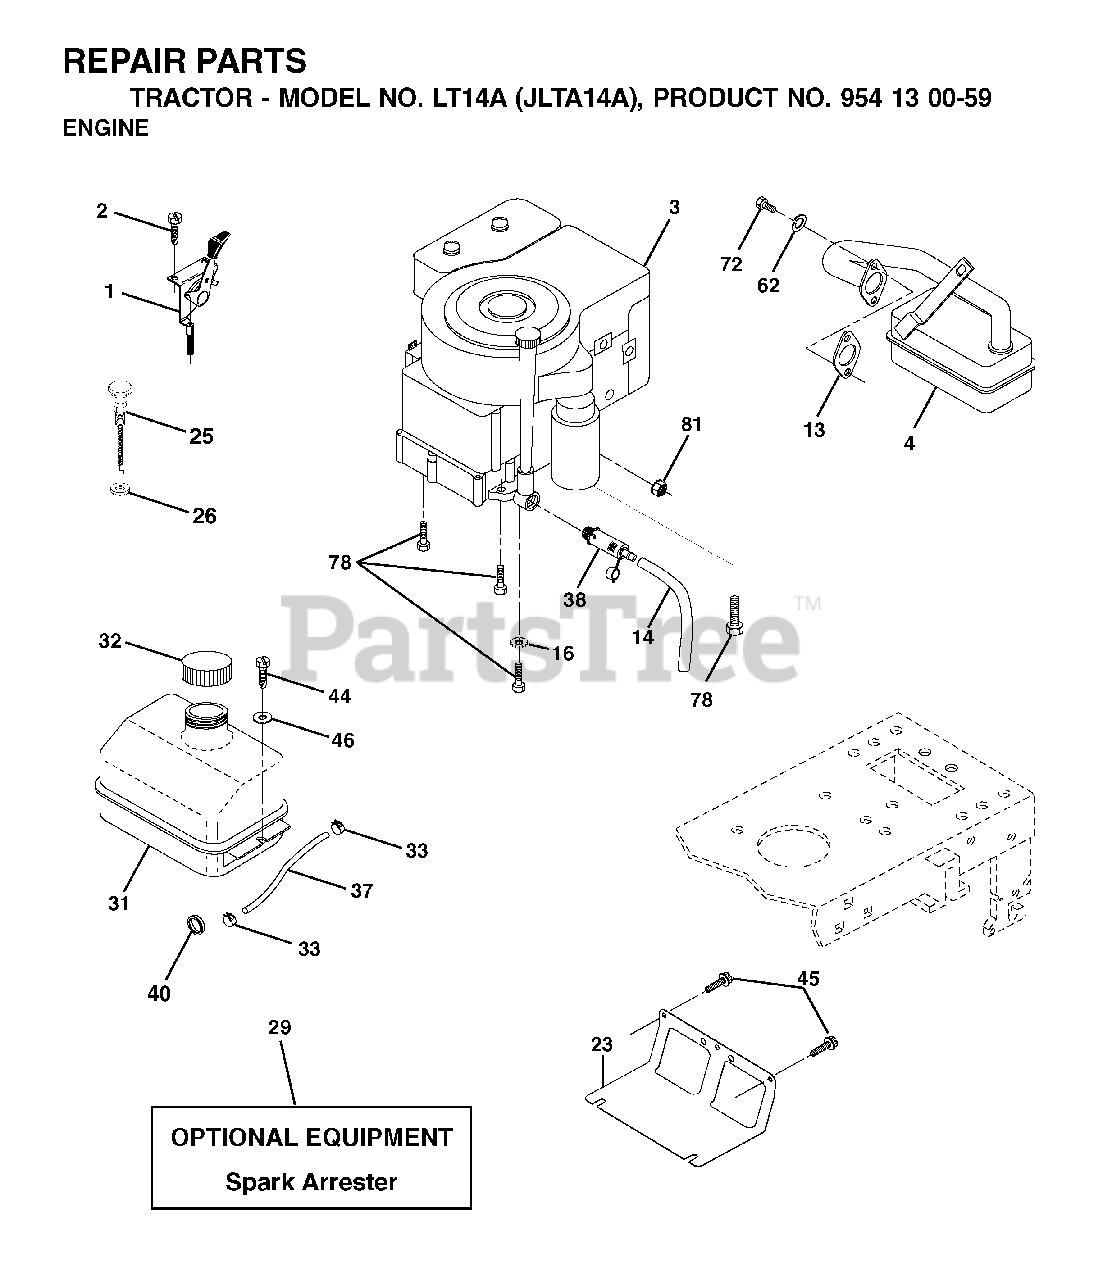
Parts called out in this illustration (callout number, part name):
1	CONTROL TH/CH FLAG
2	SCREW
13	REPL BY 532 27 22-93
14	TUBE, DRAIN OIL ASM.
16	LOCKWASHER
23	SHEILD.BROWNING.DBR.GUARD
26	NUT KEPS 3/8 - 24 UNF
29	ARRESTER SPARK (OPTIONAL)
32	FUEL CAP
33	HOSE CLAMP
37	LINE.FUEL.20
38	PLUG, OIL DRAIN EASY
40	GROMMET T
44	SCREW HEXWSHR 1/4-20X3/4
45	SCREW, 3/8-16X3/4
62	LOCKWASHER
72	SCREW
78	SCREW.3/8-16
81	NUT
